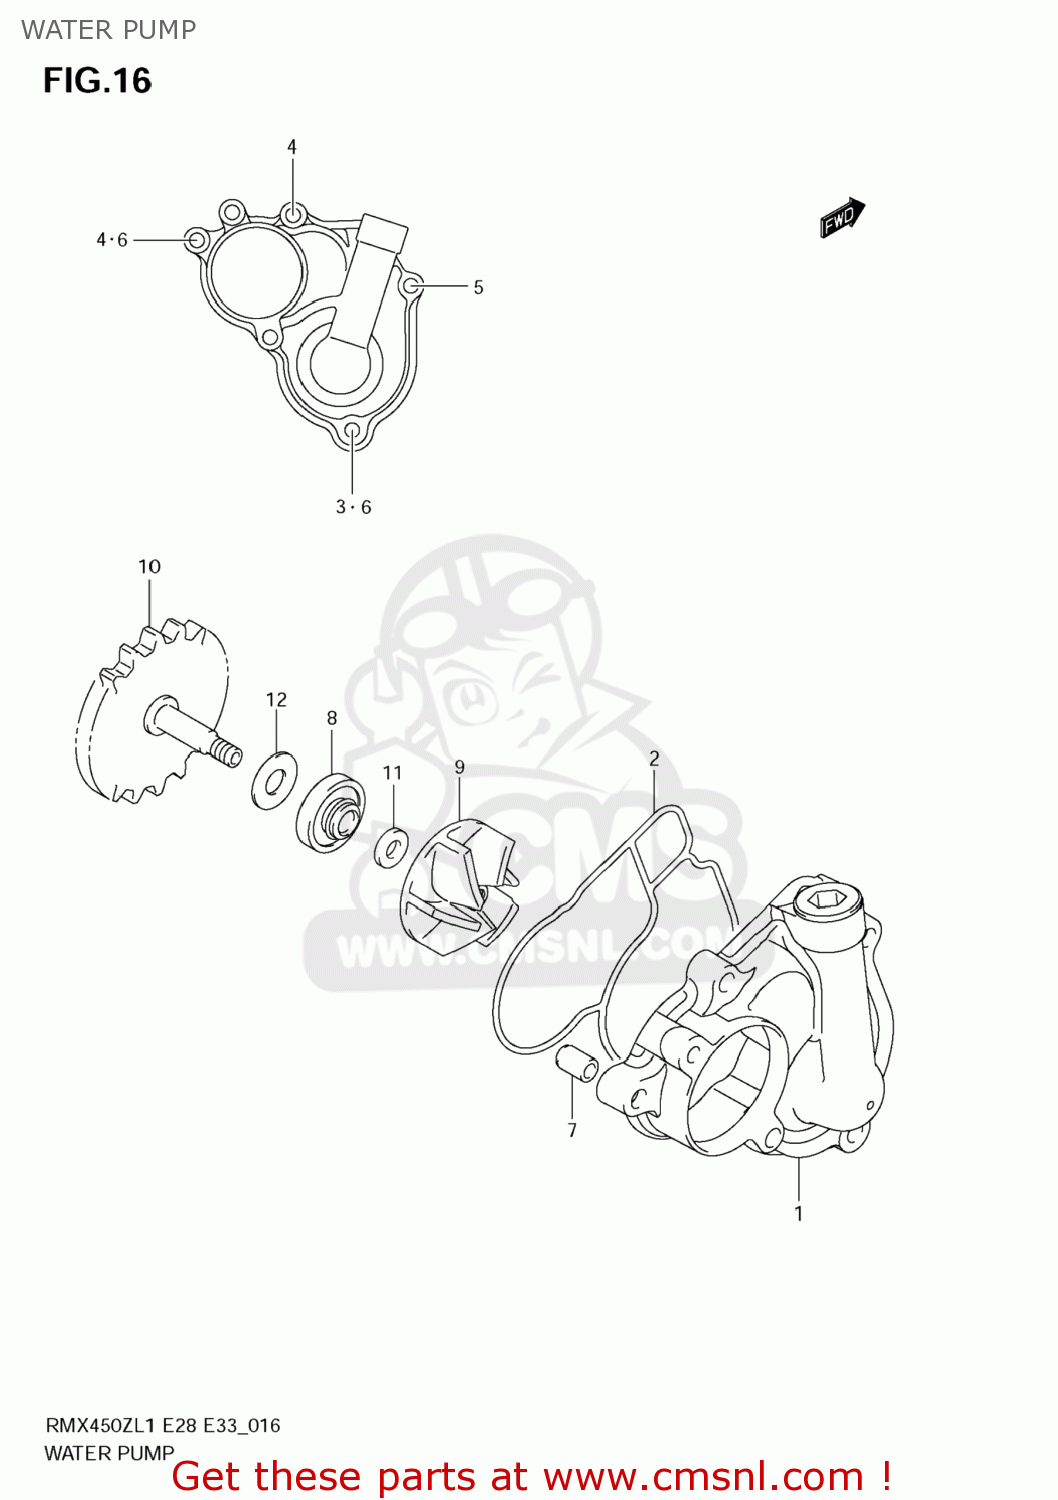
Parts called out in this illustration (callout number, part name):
1	CASE,WATER PUMP
2	O RING,WATER PUMP CASE
3	BOLT
4	BOLT
5	BOLT
6	GASKET(5.8X13X1.2) (NAS)
7	PIN(6.2X8X11)
8	SEAL,WATER PUMP OIL
9	IMPELLER,WATER PUMP
10	SHAFT,WATER PUMP
11	SHIM(6X14X1)
12	SHIM(8X18X0.5)
